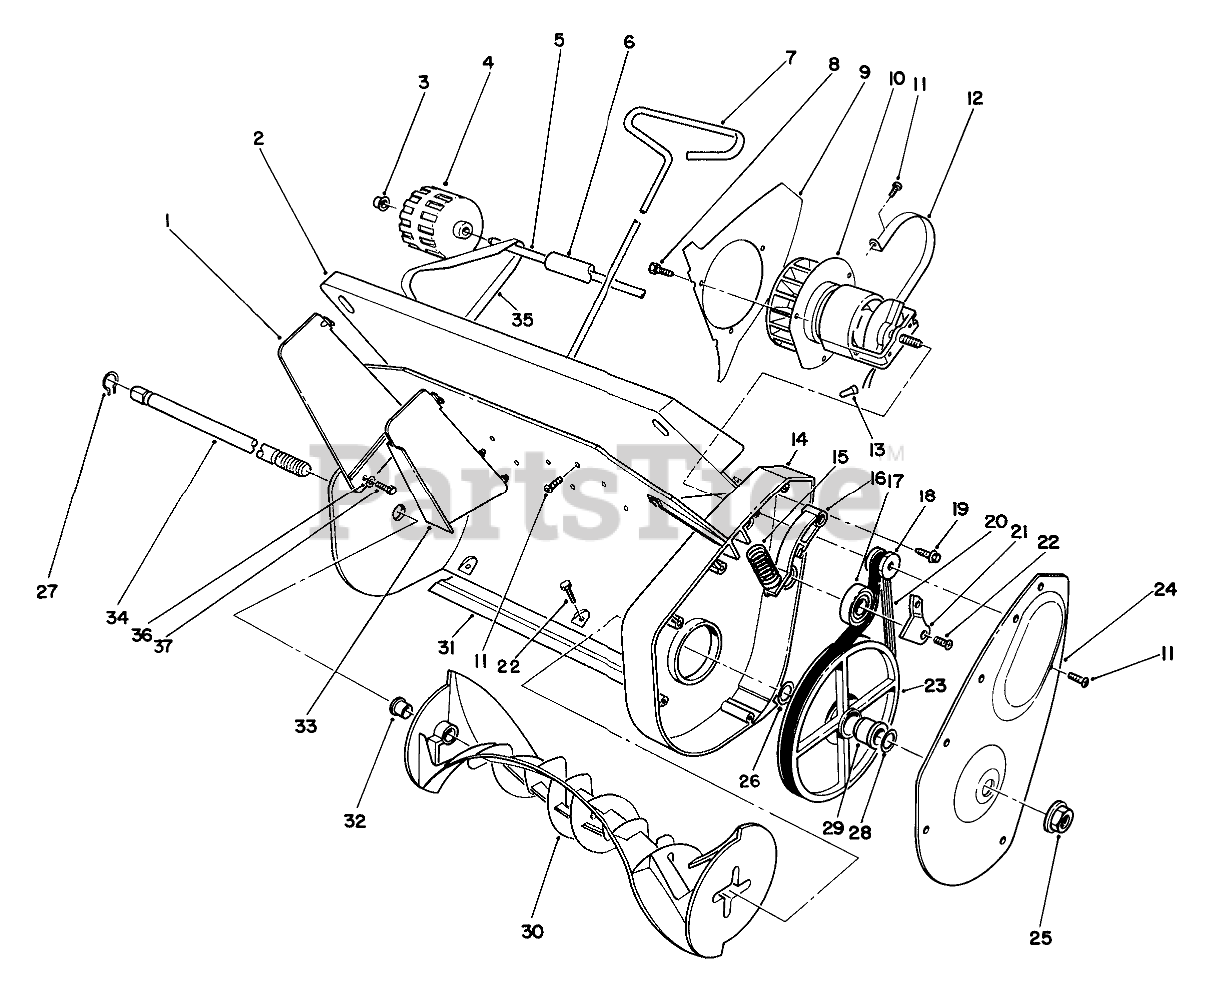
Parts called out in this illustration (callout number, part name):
1	VANE - OUTER
2	MOUNT - VANE
3	PUSHNUT-CAP, WASHER
4	Wheel
5	AXLE SHAFT
6	SLEEVE, AXLE
7	VANE ADJUSTING ROD
8	10-16 X .31 SCREW
9	AIR BAFFLE
10	MOTOR, 1200 PWR CURVE
11	Screw
12	MOTOR STRAP
13	Connector
14	HOUSING - 1200
15	SPRING
16	1200 PC - IDLER ARM
17	Bearing-Ball
18	DRIVE PULLEY
19	SCREW-HWHTF
20	BELT - DRIVE
21	1200 PC-IDLER PULL. RET
22	#8 X .625" PHILPS PAN H
23	PULLEY - DRIVEN
24	Belt Case Cover
25	NUT-HF
26	WASHER-THRUST
27	RING-RETAINING
28	THRUST WASHER (THICK)
29	DRIVEN PULLEY BUSHING
30	ROTOR, 1200
31	1200 SCRAPER, 12"
32	BUSHING-ROTOR
33	VANE - CENTER
34	ROTOR SHAFT, 1200
35	BRACKET-WHEEL,RH
36	WASHER-FLAT
37	SCREW-PPH
